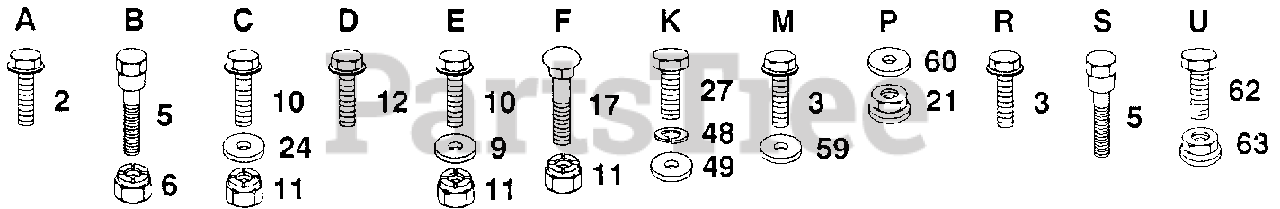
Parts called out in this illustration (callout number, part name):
2	SCREW
3	SCREW GTV
9	WASHER
12	SCREW LT
17	BOLT
21	PAL NUT LT
24	WASHER
27	BOLT
48	LOCKWASHER
49	WASHER
59	WASHER
60	WASHER PM
62	BOLT
